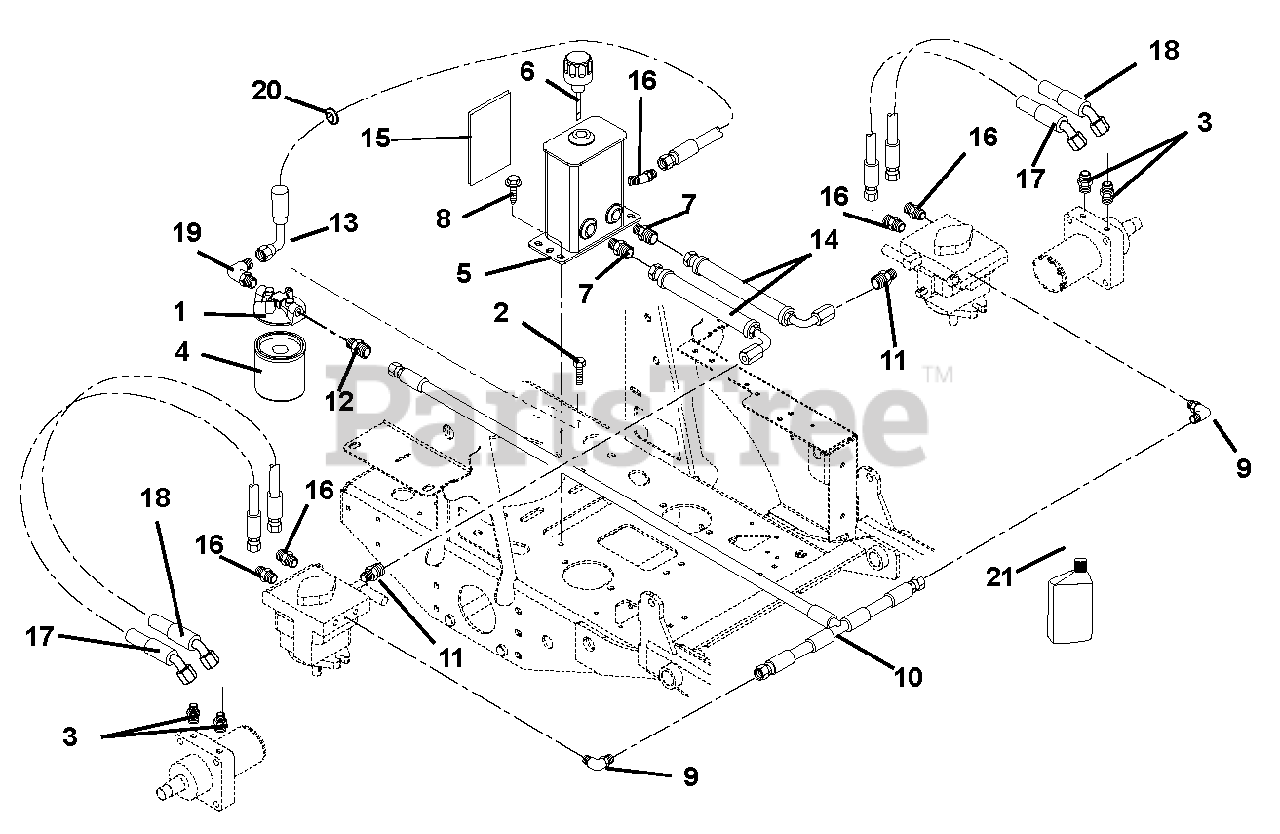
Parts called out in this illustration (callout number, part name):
1	Head, Filter
2	Bolt, Hex .25-20 x .50 Grade 5
3	Adapter, Hydraulic
4	Oil Filter
5	Weldment, Formed Hydraulic Tank - 3 Port
6	Breather Dipstick
7	Fitting, Hydraulic Straight M8O-M4F
8	Screw, Tapping .38-16 x .50 Hex Washer Head
9	Adapter, Hydraulic 8MB-12FPX90
10	Hose, Hydraulic .50 to .38 Tee Assembly
11	Fitting, Hydraulic (4-6 F5OLO)
12	Adapter, Face Seal 8 x 8 .50 O-Ring
13	Hose, Hydraulic .50-11-OK F8F0-F9F9
14	Hose, Hydraulic
15	Shield, Heat 5.50 x 4.50
16	Adapter, Face Seal 8x8 1/2 O-Ring 8 F5OLO, Steel
17	Hose, Hydraulic .50-11-3K
18	Hose, Hydraulic .50-12-3K
19	Fitting, Hydraulic EL M8F-M80
20	Grommet, 1.25ID x 1.50OD
21	Fluid, Hydraulic 15W50 Quart
